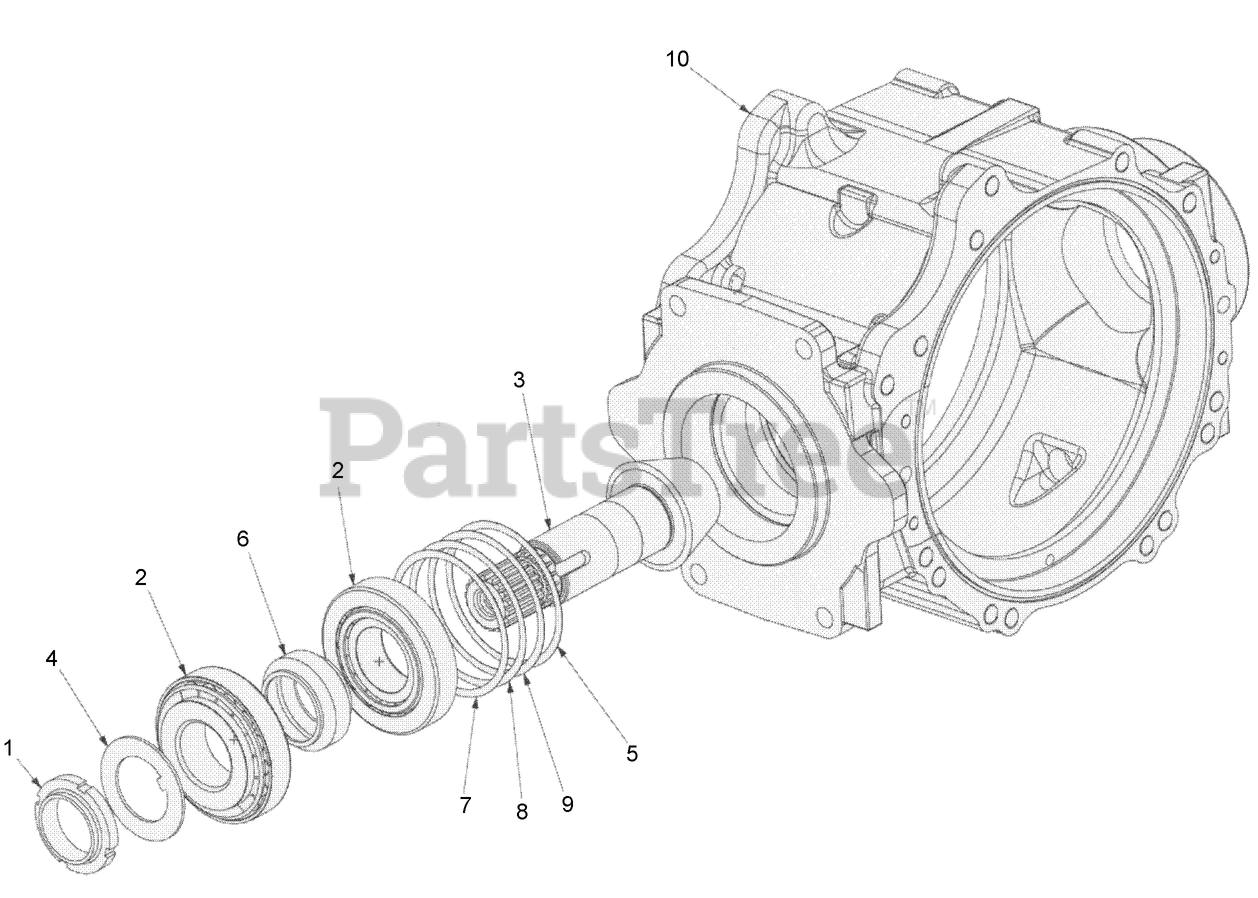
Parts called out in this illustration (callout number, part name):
2	BEARING-Roller, Taper
4	WASHER-Anti-Rotation
6	SPACER-Deformable
10	HOUSING-Central
